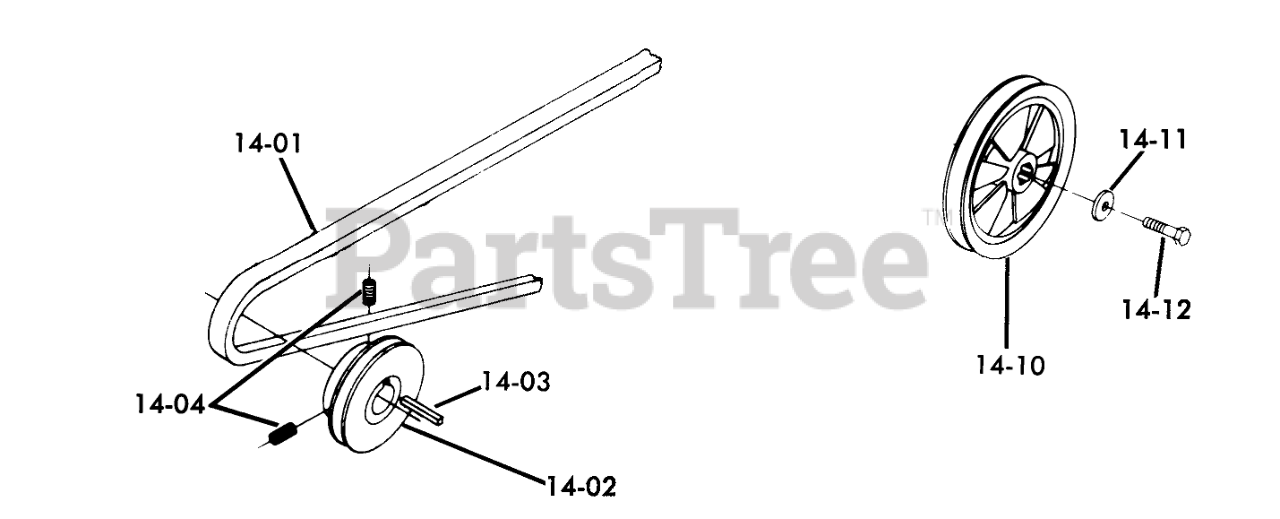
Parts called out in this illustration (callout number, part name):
14-01	V BELT
14-02	PULLEY
14-04	Set Screw
14-10	PULLEY
14-11	WASHER
14-12	Bolt
